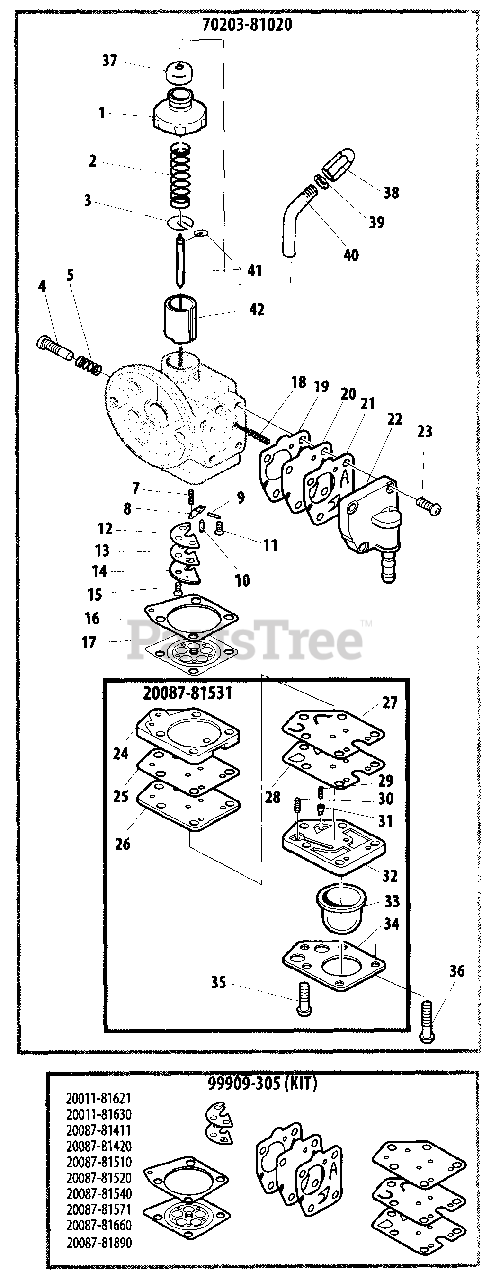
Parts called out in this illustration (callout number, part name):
1	CAP, CARBURETOR
2	SPRING
3	WASHER, SPRING SUPPORT
4	SCREW, IDLE ADJUST
5	SPRING
7	SPRING
8	LEVER, METERING
9	PIN, METERING LEVER
10	VALVE, INLET NEEDLE
11	SCREW M3×8
12	GASKET
13	VALVE, CHECK
14	PLATE
15	SCREW M3×8
16	GASKET, METERING DIAPHRAGM
17	DIAPHRAGM, METERING
18	SPRING, COIL
19	GASKET, DIAPHRAGM
20	DIAPHRAGM, METERING
21	VALVE, PUMP
22	PUMP BODY
23	SCREW
24	COVER, PUMP
25	GASKET
26	PLATE, PUMP
27	VALVE, CHECK
28	GASKET
29	SPRING
30	SPRING
31	VALVE, CHECK
32	COVER, PUMP
33	BULB, PURGE
34	RETAINER, PURGE BULB
35	SCREW
36	SCREW 3×20
37	CAP, DUST
38	ADJUSTER, CABLE
39	NUT, LOCK
40	PIPE, CABLE ADJUSTER
41	NEEDLE, JET
42	VALVE, SLIDE
20087-81531	PURGE PUMP KIT
70203-81020	CARBURETOR
99909-305	DIAPHRAGM/GASKET KIT
